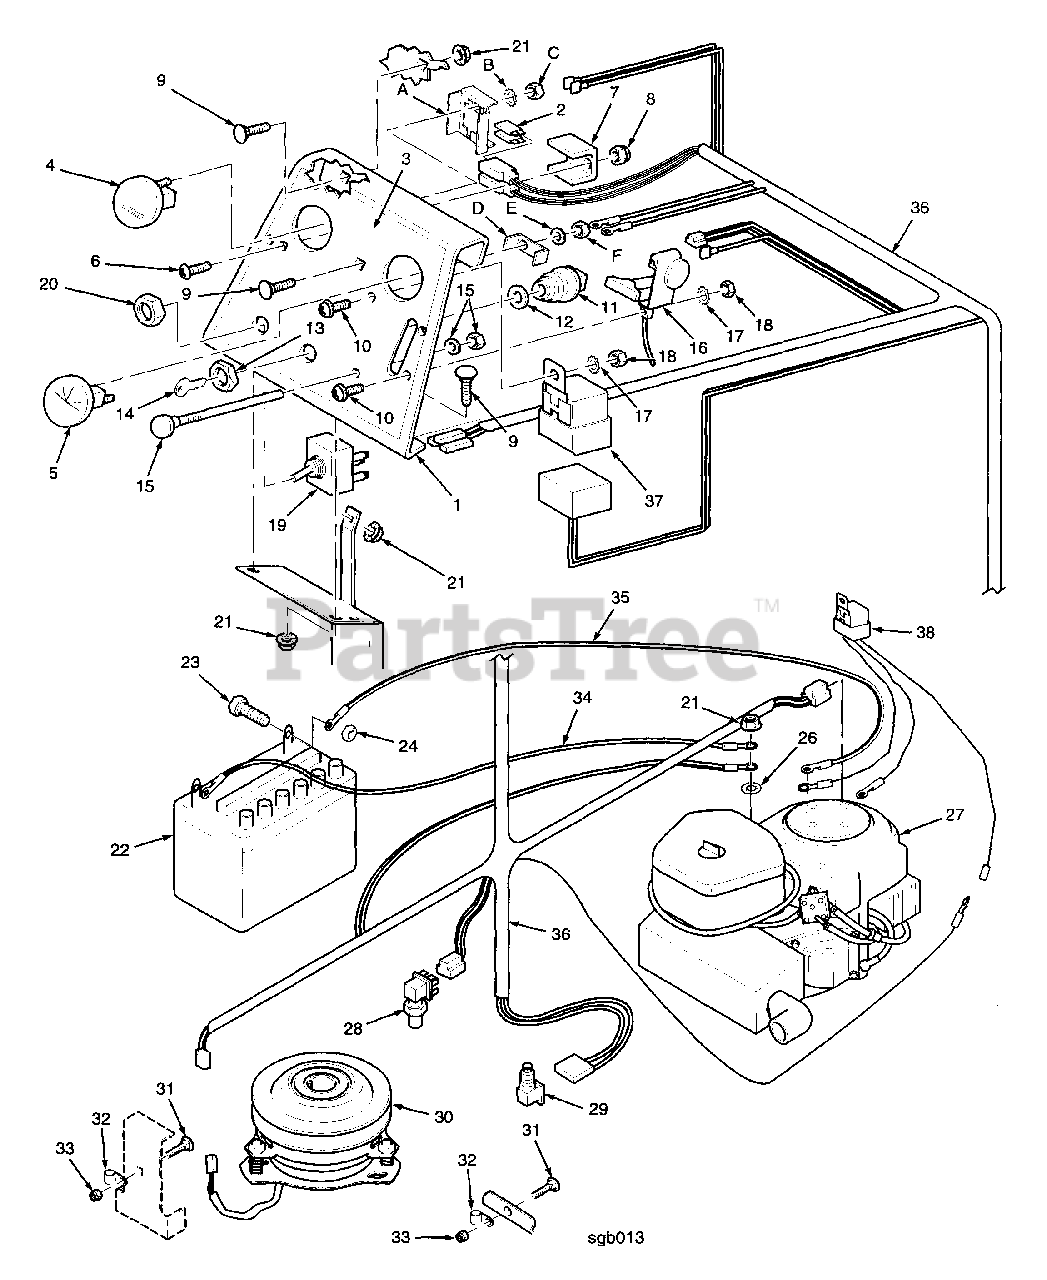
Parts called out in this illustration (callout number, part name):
1	Instrument Panel
2	Blade Fuse, 20 amp
3	Decal, Instrument Panel
4	Hour Meter
5	Ammeter
6	Phillips Rd Head Screw, #10-32 x 1-1/2
7	Bracket, Fuse Holder
8	Elastic Stop Nut, #10-32
9	Carriage Bolt, 5/16-18 x 3/4
10	Phillips Washer Head Screw, #10-32 x .50
11	Keyswitch
12	Lockwasher, 5/8 Int. Tooth
14	Ignition Key and Ring Assy.
15	Choke Control
16	Throttle Control
17	Lockwasher, #10 Ext. Tooth
18	Hex Nut, #10-32
19	Switch, PTO
21	Serr. Fl. HH Nut, 5/16-18
22	Battery
23	Bolt, Hex head 1/4-20 x 1/2
24	Hex Nut 1/4-20
26	Lockwasher 5/16 Int Tooth
27	Engine, 20 HP Kohler CV
28	Switch, Parking Brake
29	Switch, Foot Safety
30	Clutch, Electric
31	Carriage Bolt, 5/16-18 x 3/4
32	Wireloom
33	Locknut, Elastic Stop 5/16-18
34	Battery Cable, 36" Black
35	Battery Cable, 25" Red
36	Wire Harness, STHM
37	Relay
38	Wire Harness With Relay
A	Hour Meter Bracket
B	Lockwasher, #10 Ext Tooth
D	Ammeter Bracket
E	Lockwasher, #10 Int. Tooth
